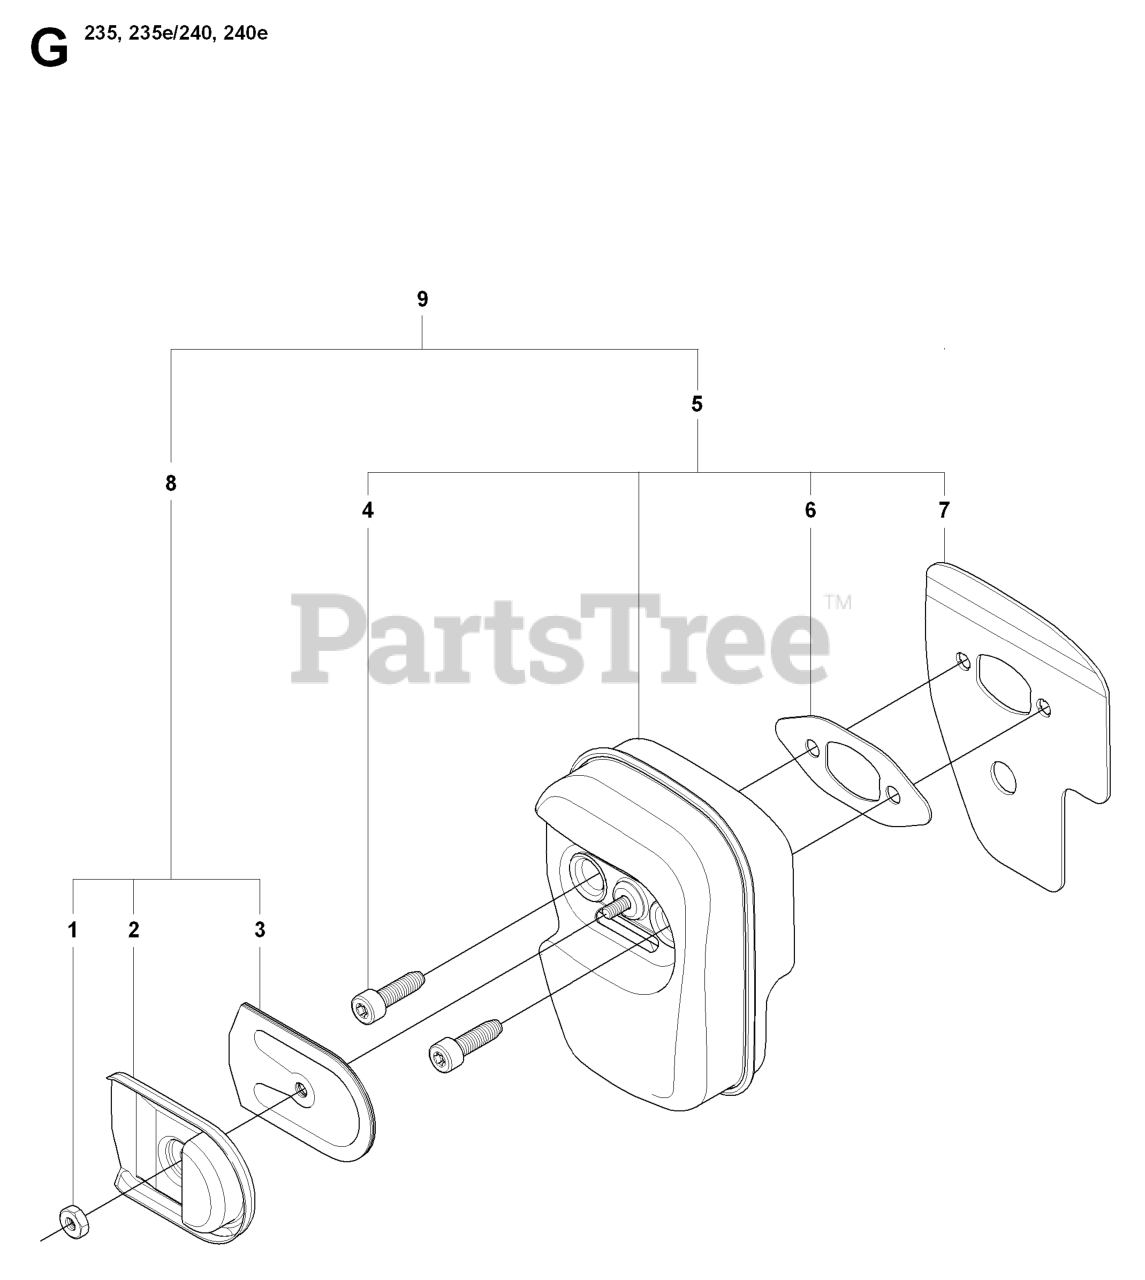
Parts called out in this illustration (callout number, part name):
1	NUT-BRASS
2	EXHAUST PLATE
3	SCREEN ARRESTOR
4	SCREW MUFFLER
5	MUFFLER ASSY
8	KIT SPARK ARRESTOR
9	MUFFLER KIT
